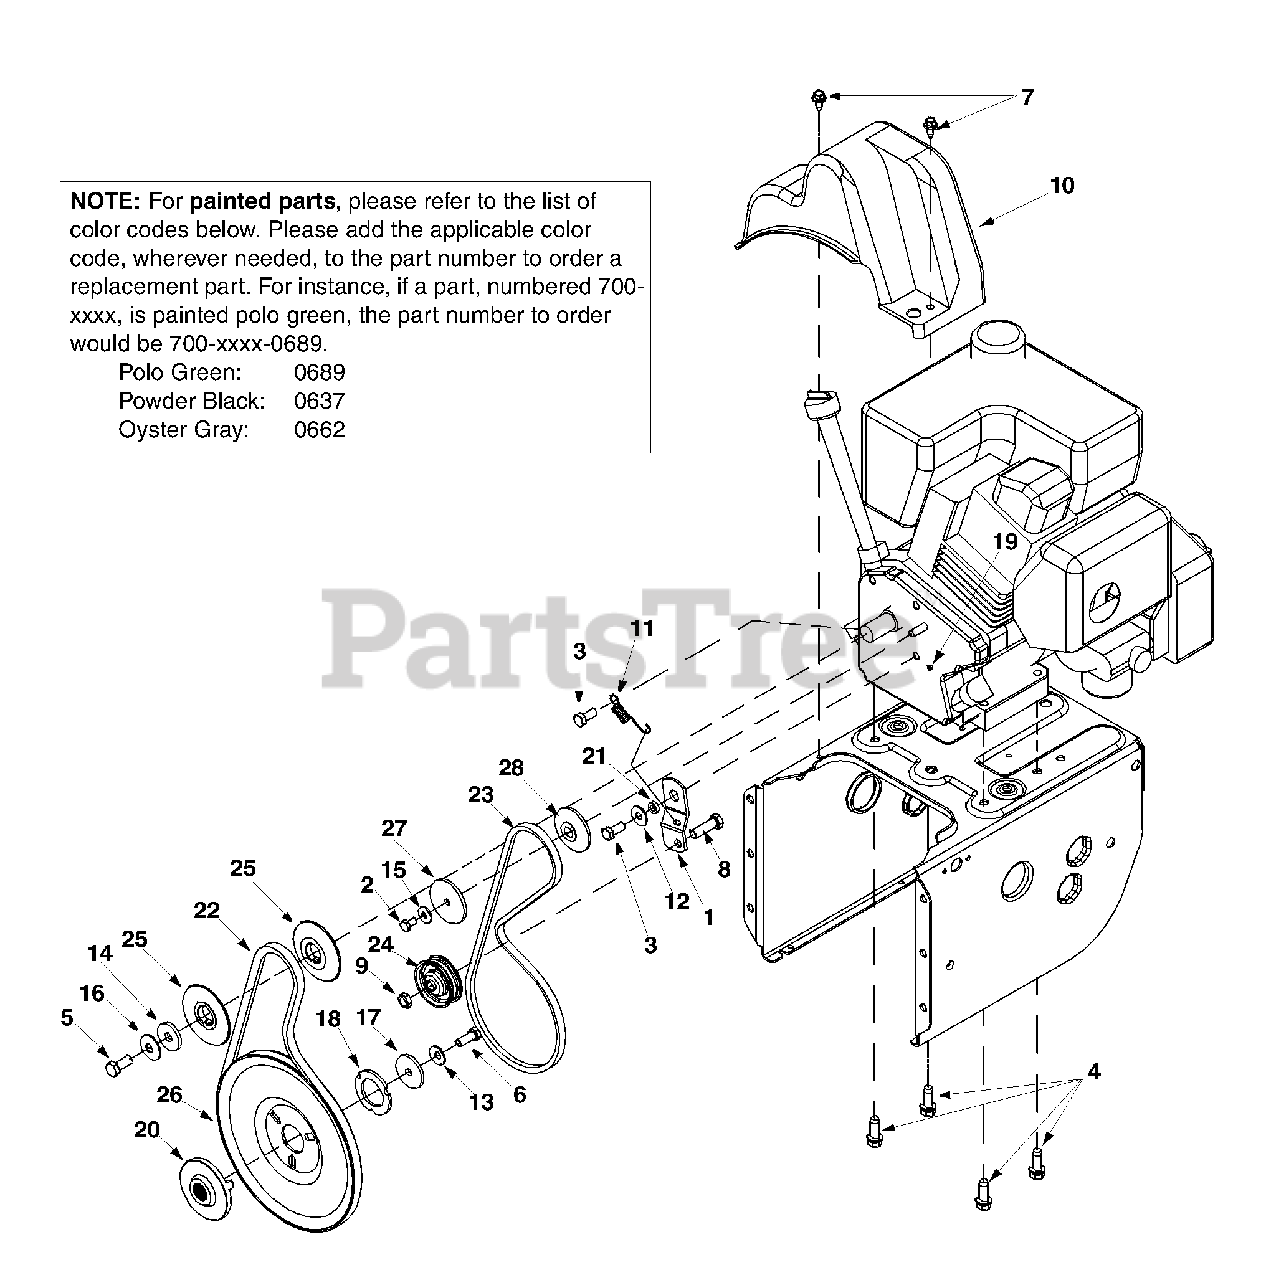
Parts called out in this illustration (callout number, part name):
3	Lock Screw 5/16-24 x 0.750"
4	TT Sems Screw
5	Hex Screw 3/8-24 x 0.875"
6	Lock Screw 5/16-24 x 0.875"
7	TT Screw 1/4-20 x 0.625"
8	Hex Screw 3/8-16 x 1.25"
9	Jam Nut
10	Belt Cover
11	Extension Spring
12	Washer
13	Beleville Washer
14	Flat Washer
15	Bell Washer
16	Bell Washer
17	Flat Washer
18	Special Washer
19	Grease
20	Pulley
21	Spacer
22	Belt
23	V-Belt
24	Flat Idler
25	Pulley Half
26	Auger Pulley
27	Pulley Half
28	Pulley Half
